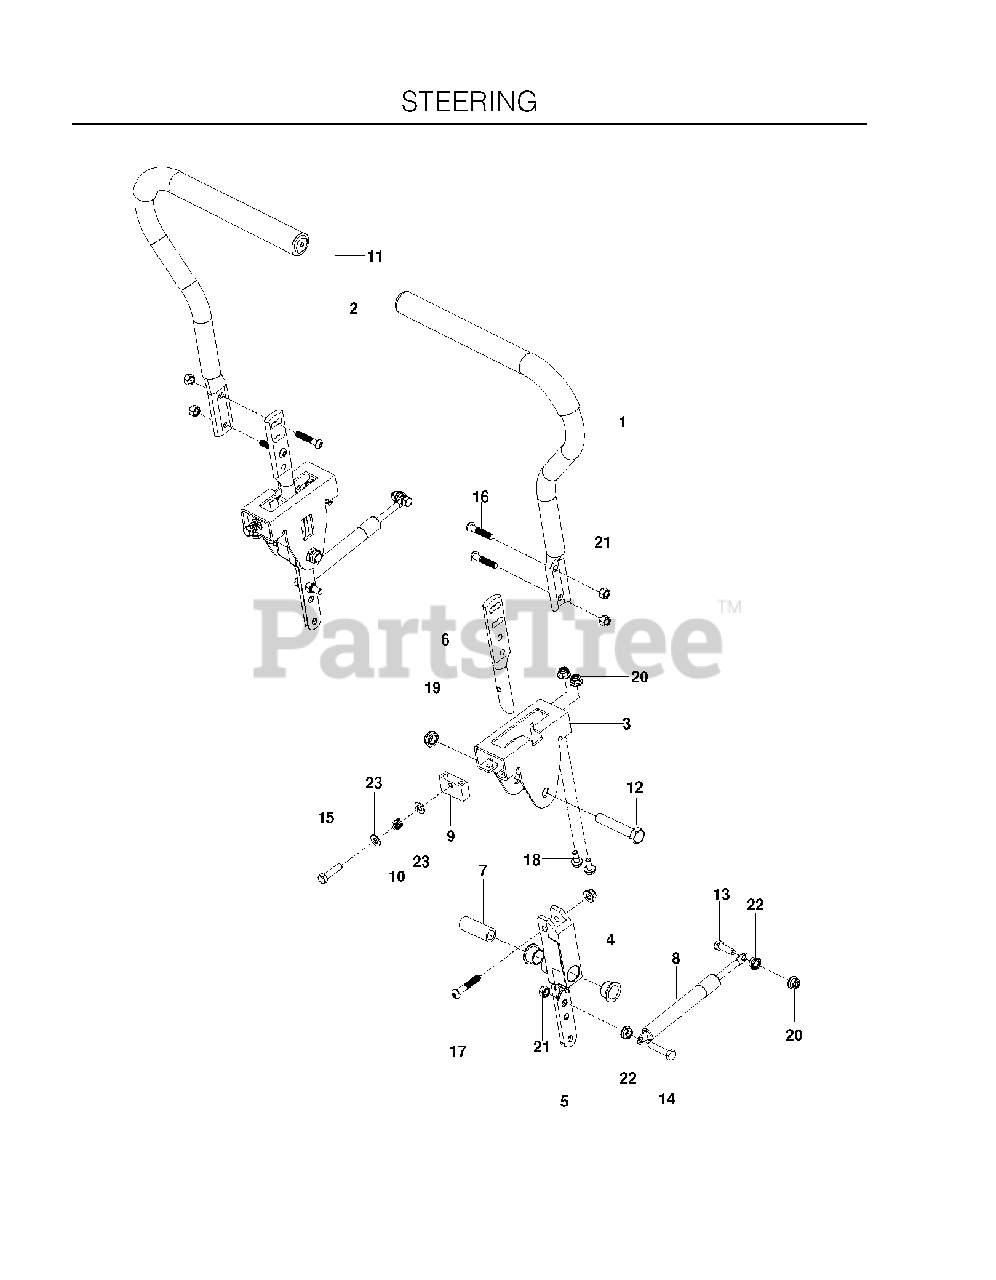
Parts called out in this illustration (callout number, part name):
2	GRIP, FOAM (GROUND) 15
4	BEARING, FLANGE
8	DAMPENER
11	END PLUG 15/16` (BLACK)
12	HCS 1/2C X 2 3/4
13	HCS 5/16C X 1
14	HCS 5/16-18X1-3/4 TPBLT
15	CAPSCREW 5/16 X 1/1/2 HEX HEAD
18	HHFS 5/16-18 X 3/4
19	NUT 1/2-13 HEX JM NYL
20	5/16-18 NYLOC FLANGE NUT
21	NUT 5/16 NYLOC
22	NUT 5/16C WHIZ
23	FLAT WASHER 5/16 SAE
